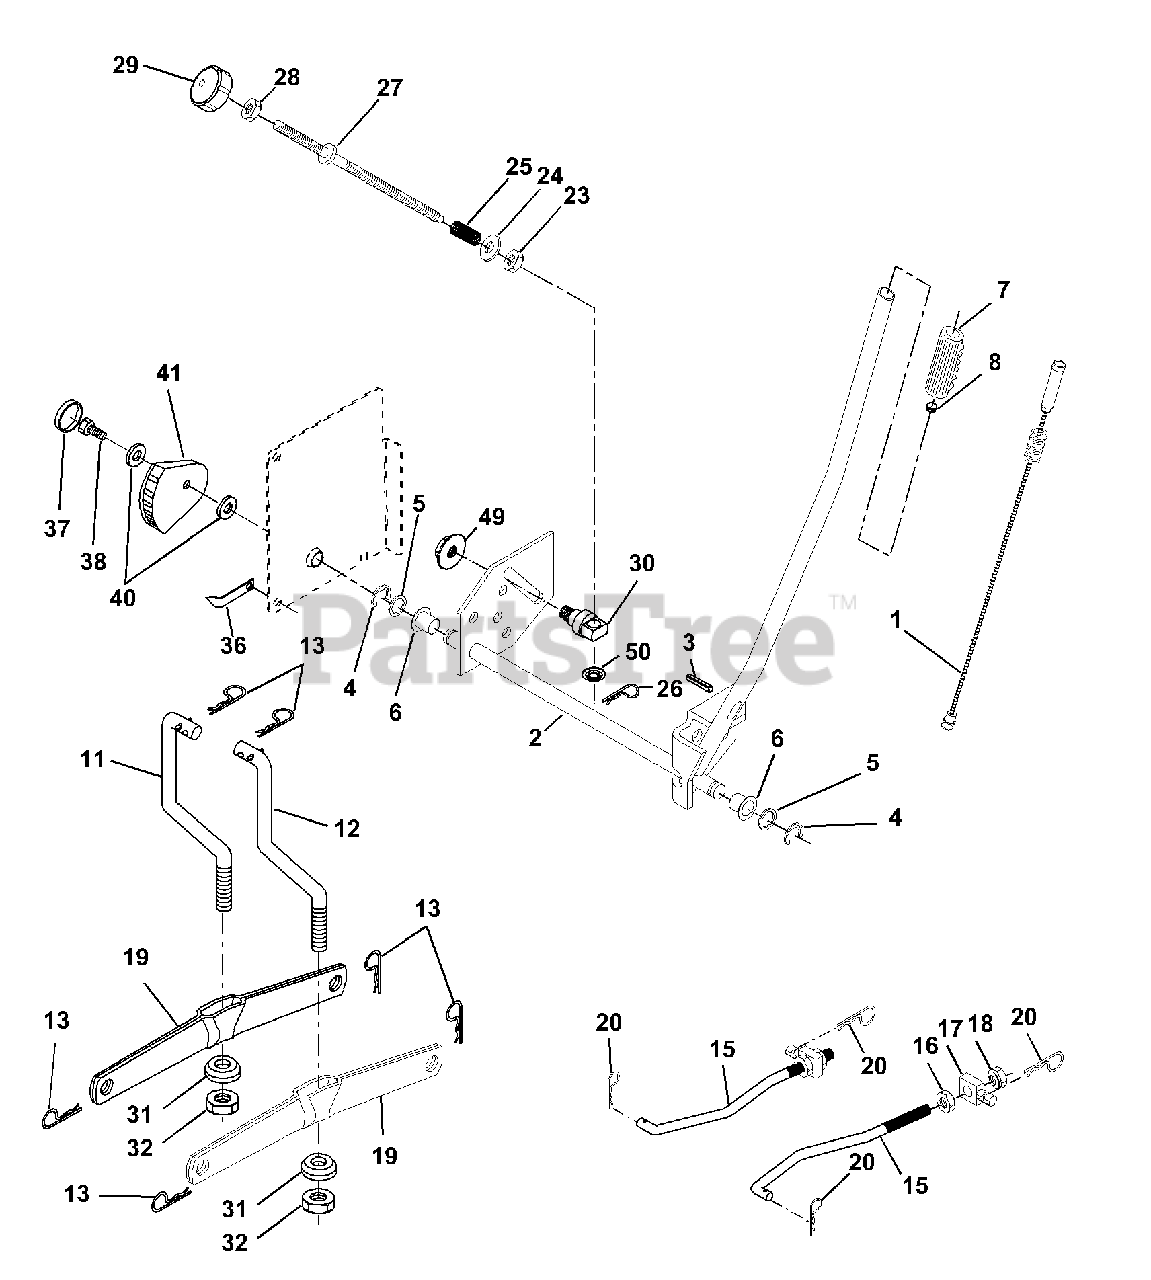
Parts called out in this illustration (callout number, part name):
1	Wire Asm Inner W/plunger
2	Shaft Asm Lift RH w/Inf
3	Pin Groove 1 500 Zinc
4	E Ring #5133-62
5	Washer 21/32 X 1 X 21 Ga
6	Bearing Nylon Blk 629 Id
7	Grip Handle Fluted Blk
8	Button Plunger Black
11	Link Lift LH Fixed Length
12	Link Lift RH Fixed Length
13	Retainer Spring
15	Link Front
16	Nut Jam Hex 1/2-13 Unc
17	Trunnion Blk Zinc
18	Nut Lock w/Wsh 1/2-13unc
19	Arm Suspension Rear
20	Retainer Spring
23	Nut Special
24	Washer 13/32 X 5/8 X 16 Ga
25	Spring 2-1/8"
26	Retainer Clip
27	Rod Adj Lift Zinc 7.49 Wrk Lg
28	Nut Hex Jam 3/8-16 Unc
29	Knob Inf 3/8-16 Unc Blk W/sym
30	Trunnion Infin Height
31	Bearing Pvt Lift
32	Nut Crownlock 3/8 - 24
36	Pointer Height Indicator
37	Plug Hole Blk 1.485/1.515 Dia.
38	Screw 5/16-18 x 1
40	Washer 11/32 x 1-1/2 10 Ga.
41	Indicator Height STLT
49	Nut Hex Flange Lock
50	Nut Phos & Oil
